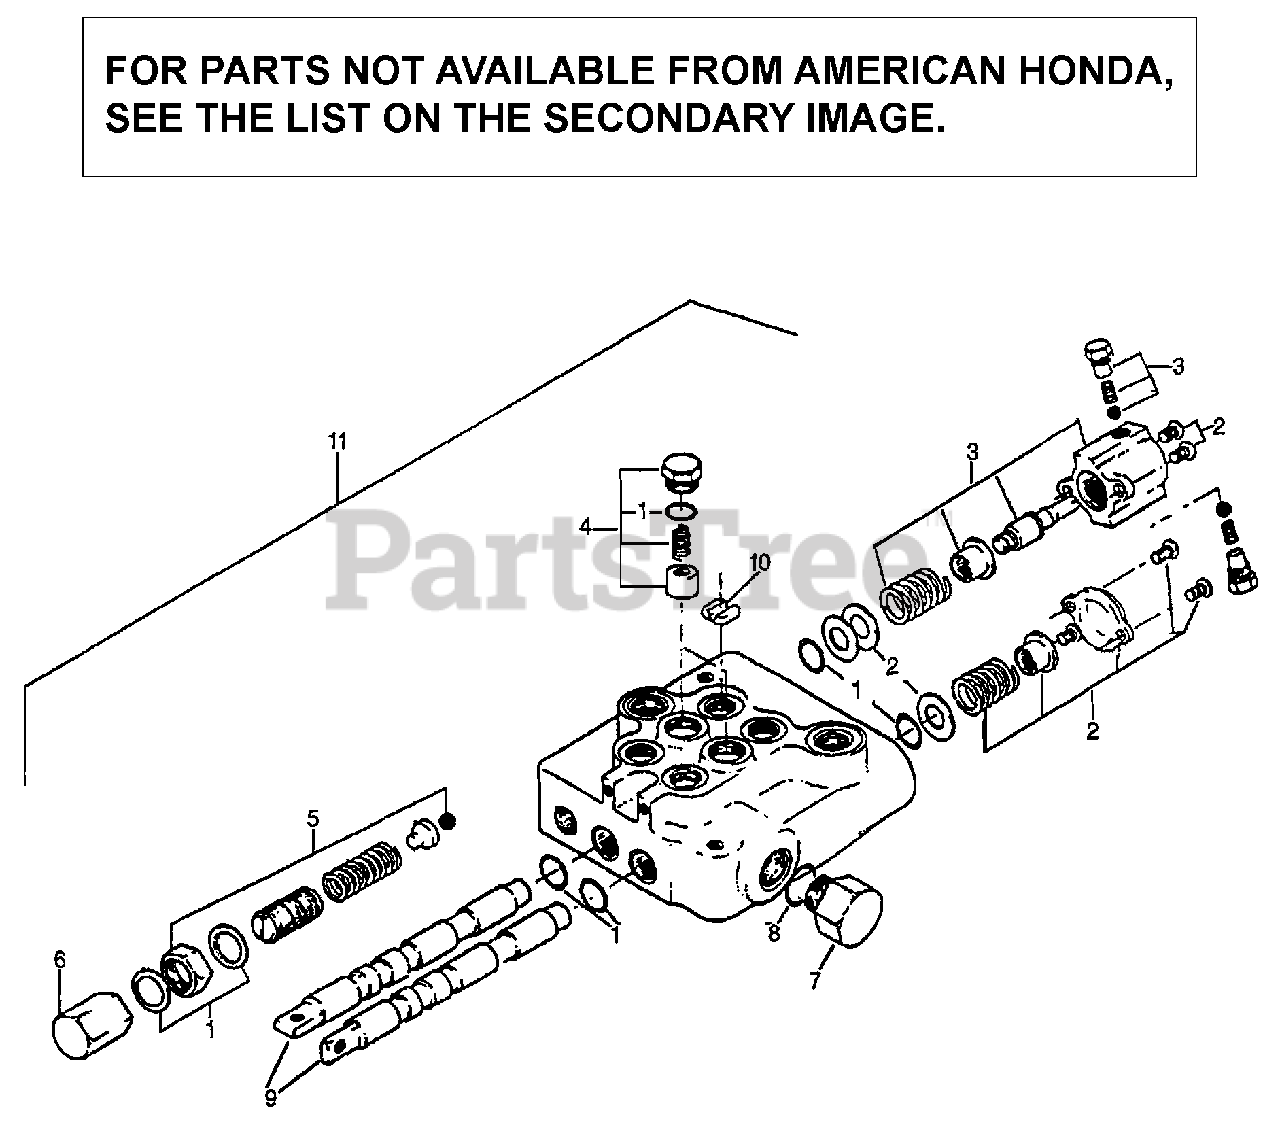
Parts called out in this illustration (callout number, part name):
1	REPAIR KIT, SEAL
2	CENTERING KIT, SPRING
3	REPAIR KIT, DETENT CHECK (NOT AVAILABLE)
4	REPAIR KIT, LOAD CHECK (NOT AVAILABLE)
5	REPAIR KIT, RELIEF VALVE
10	PLATE, ORIFICE (NOT AVAILABLE)
11	VALVE ASSY., HYDRAULIC
